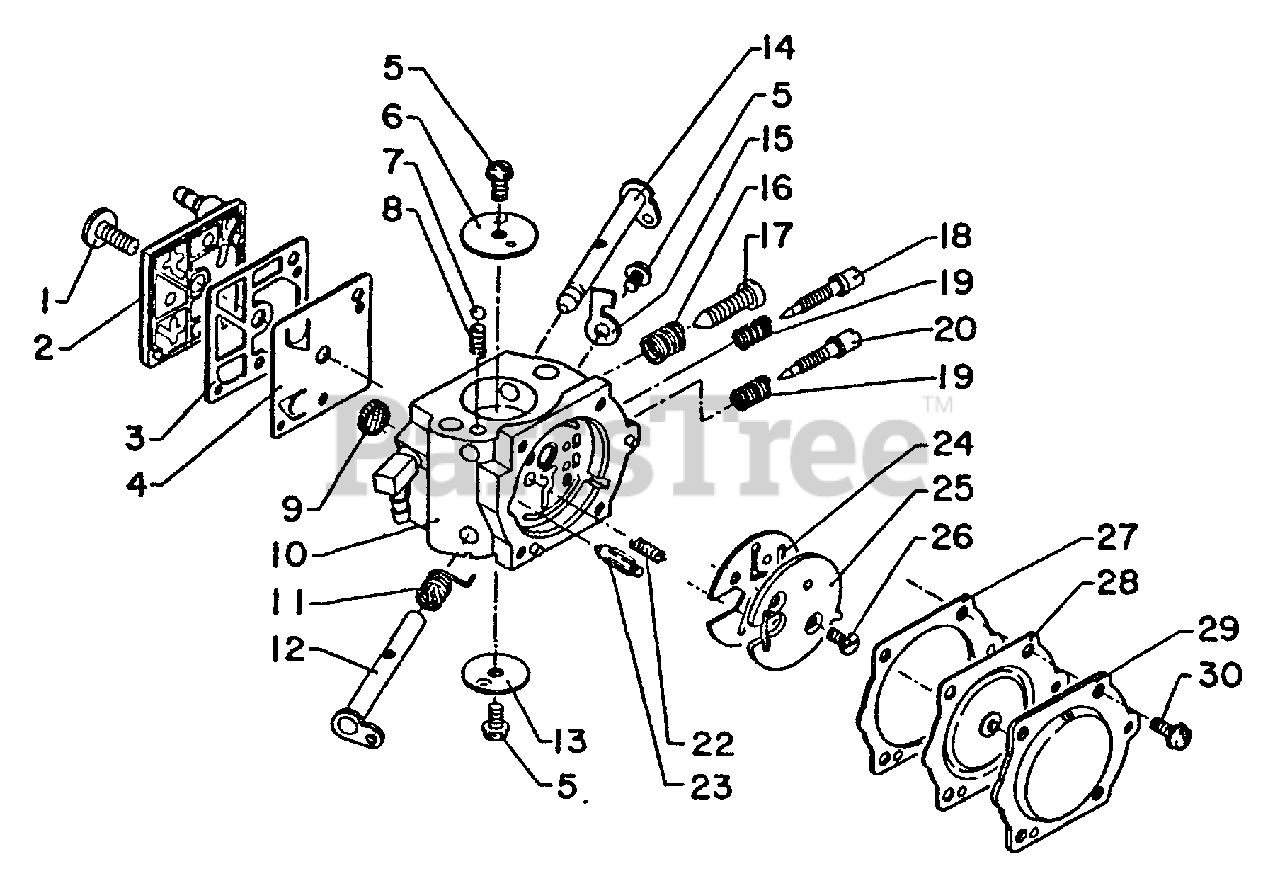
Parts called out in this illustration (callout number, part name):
2	COVER, PUMP
3	GASKET, FUEL PUMP
4	DIAPHRAGM, FUEL PUMP
6	VALVE, CHOKE
7	BALL, CHOKE FRICTION
9	SCREEN, FUEL INLET
10	BODY, CARBURETOR
11	SPRING, THROTTLE
12	SHAFT, THROTTLE
13	VALVE, THROTTLE
14	SHAFT, CHOKE
15	STOP, THROTTLE
16	SPRING, IDLE ADJUST
17	SCREW, IDLE ADJUST
18	NEEDLE, IDLE
19	SPRING, NEEDLE
20	NEEDLE, HIGH SPEED
23	VALVE, INLET NEEDLE
24	GASKET, CIRCUIT PLATE
25	PLATE, CIRCUIT
26	SCREW, CIRCUIT PLATE
27	GASKET, METERING DIAPHRAGM
28	DIAPHRAGM, METERING
29	COVER, DIAPHRAGM
